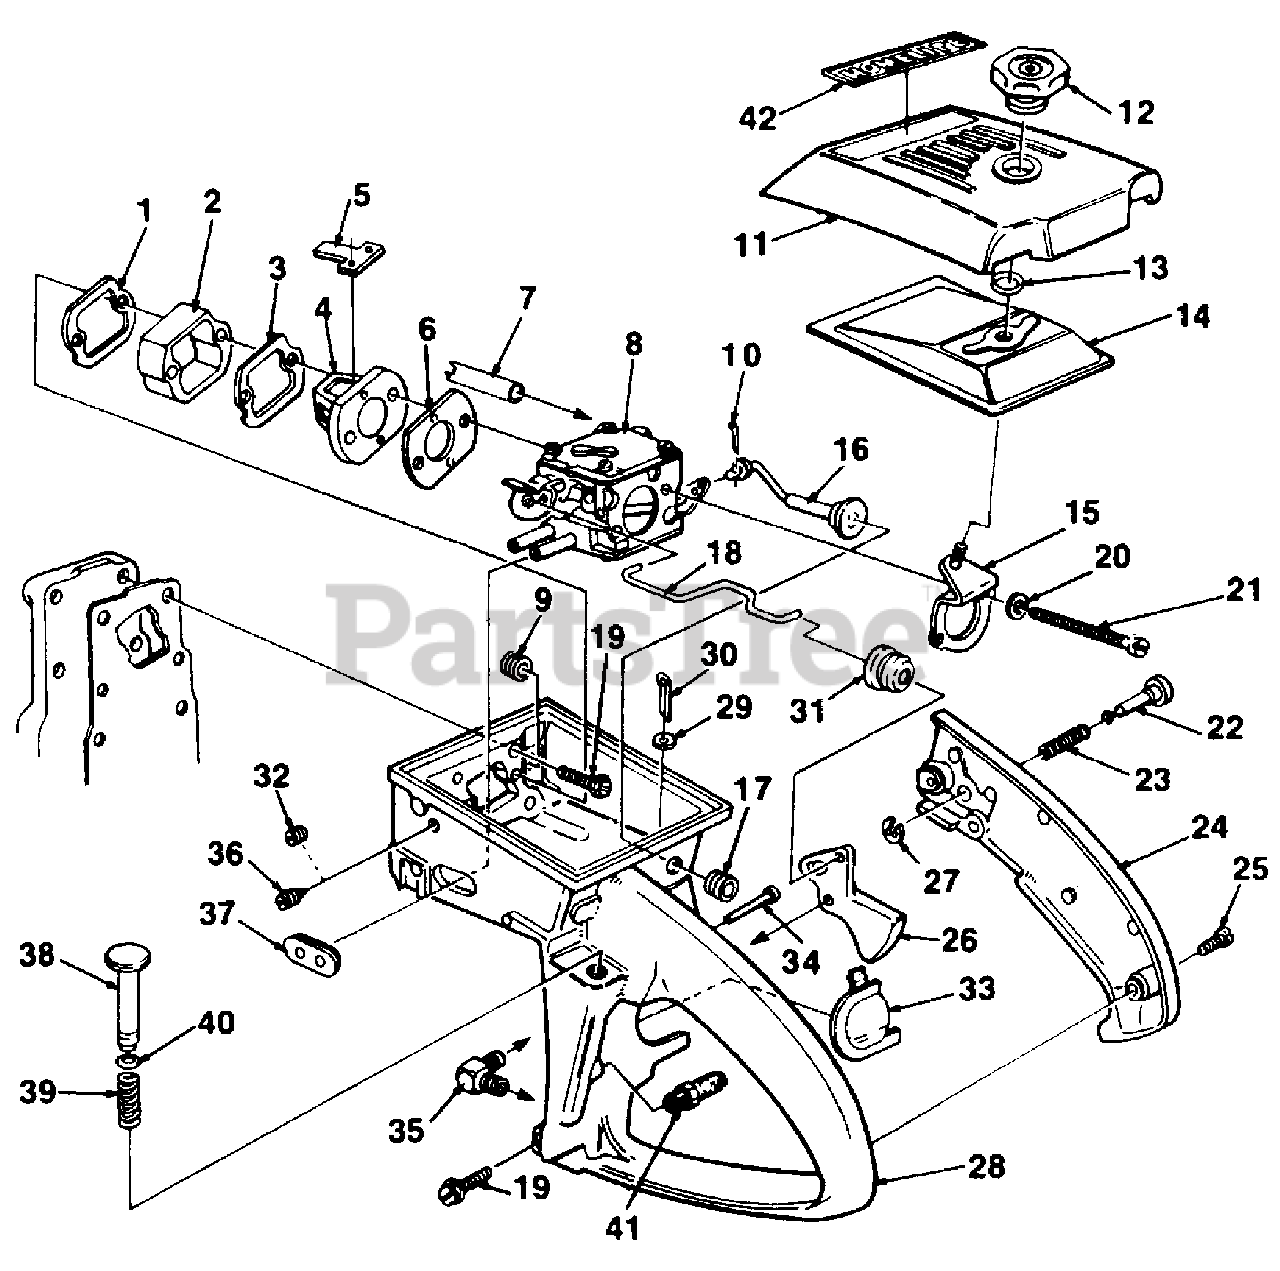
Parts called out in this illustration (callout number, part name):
1	GASKET- Spacer
3	RETAINER- Reed valve
4	SEAT- Reed valve
5	VALVE- Reed
6	GASKET- Carburetor
7	LINE- Fuel 9 1/4"
8	CARBURETOR- Walbro (SDC-62)
9	GROMMET
10	PIN- Cotter
11	COVER-Air filter
12	NUT- Air filter cover
13	RING- Retaining
14	ELEMENT- Air filter
15	BRACKET- Mounting
16	ROD- Choke
17	GROMMET
18	ROD- Throttle
19	SCREW- Hex 12-24 x 7/8
20	WASHER- Lock #10
21	SCREW- Hex 10-32 x 2 11/16
22	PIN- Throttle latch
23	SPRING- Throttle latch
24	COVER- Throttle handle
25	SCREW- Pan 8-32 x 1/2
26	TRIGGER- Throttle
27	RING- Retaining
28	THROTTLE HANDLE
29	WASHER- Felt
30	PIN- Cotter
31	BOOT- Throttle rod
33	SHIELD- Spark plug
35	VALVE- Check
36	SCREW- Idle
37	GROMMET- Hi-Lo
38	PLUNGER- Spring
39	SPRING- Compression
40	"O" RING
42	LABEL- Homelite
